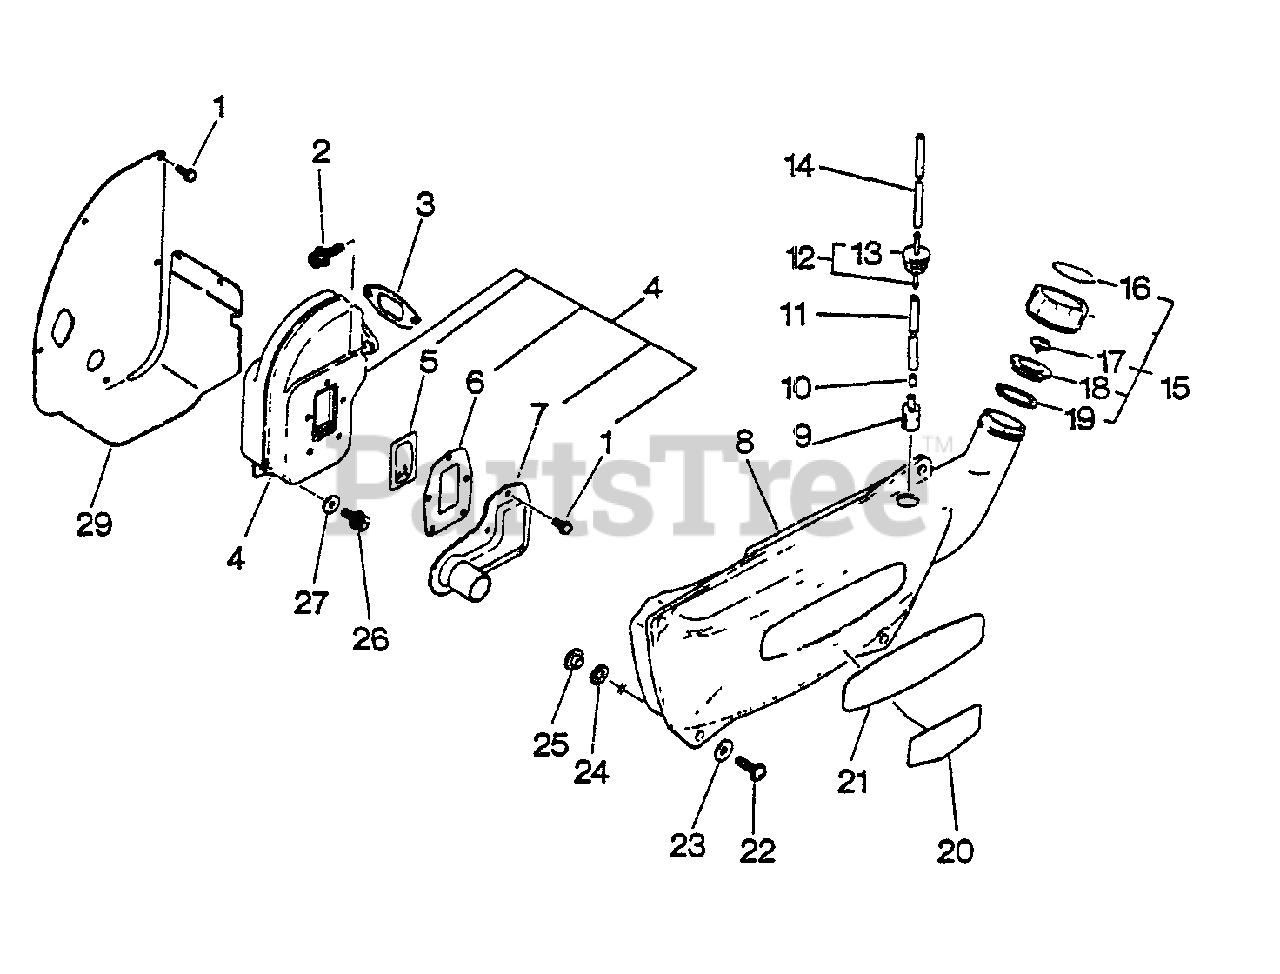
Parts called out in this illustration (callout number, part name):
1	SCREW - 4X10
2	SCREW - 6X20
3	GASKET, EXHAUST
4	MUFFLER ASSY
5	SCREEN, SPARK ARRESTOR
6	GASKET, EXHAUST
7	GUIDE, EXHAUST
8	TANK, FUEL
9	FILTER, FUEL
11	PIPE - FUEL
12	GROMMET KIT
14	PIPE - FUEL
15	CAP ASSY
16	LABEL - FUEL MIX
18	HOLDER, VENT
19	GASKET, CAP
20	LABEL - MODEL
21	LABEL - ECHO
22	SCREW - 5X20
24	WASHER - RUBBER
26	SCREW - 5X14
27	WASHER - 5
28	INSULATOR
